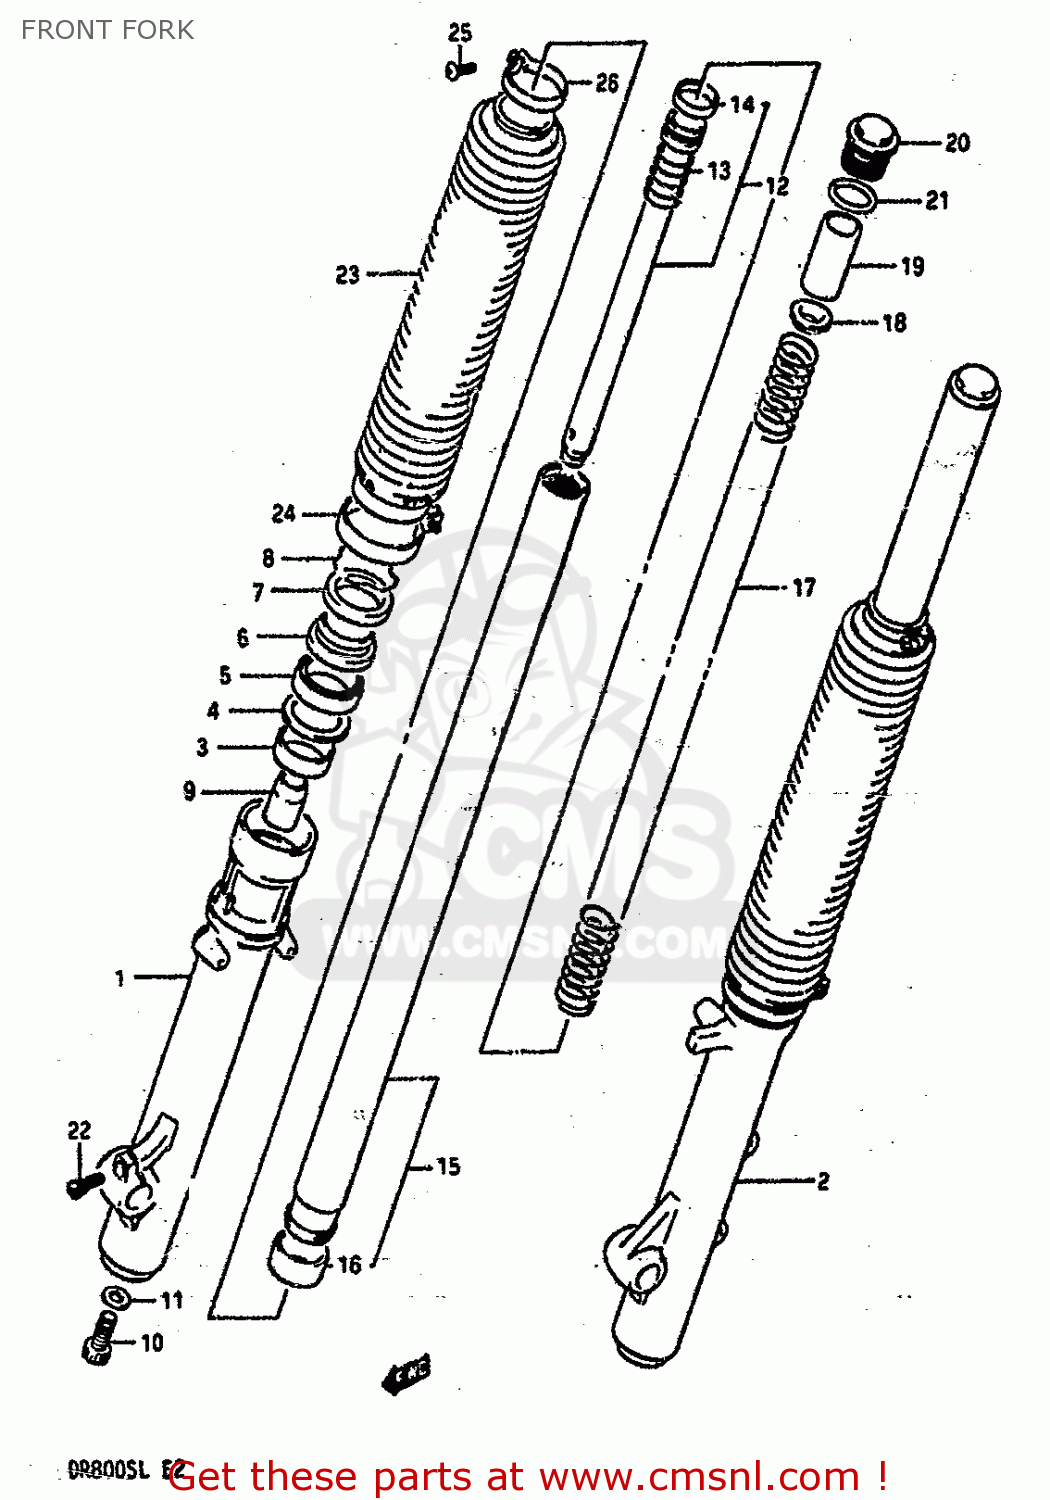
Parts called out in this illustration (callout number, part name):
1	TUBE,OUTER RH
2	TUBE,OUTER LH
3	METAL,SLIDE
4	WASHER,FORK OIL SEAL
5	SEAL,OIL
6	SEAL,DUST
7	WASHER
8	RING,OIL SEAL STOPPER
9	PIECE,OIL LOCK
10	BOLT,CYLINDER
11	GASKET,CYLINDER (NAS)
12	CYLINDER
13	SPRING,REBOUND
14	RING,FRONT FORK PISTON
15	TUBE,INNER
16	PISTON
17	SPRING
18	GUIDE,SPRING
19	SPACER
20	BOLT,FORK
21	O RING
22	BOLT,SOCKET HEAD(8X22)
23	BOOT
24	BAND,BOOT LWR
25	SCREW
26	BAND,BOOT
